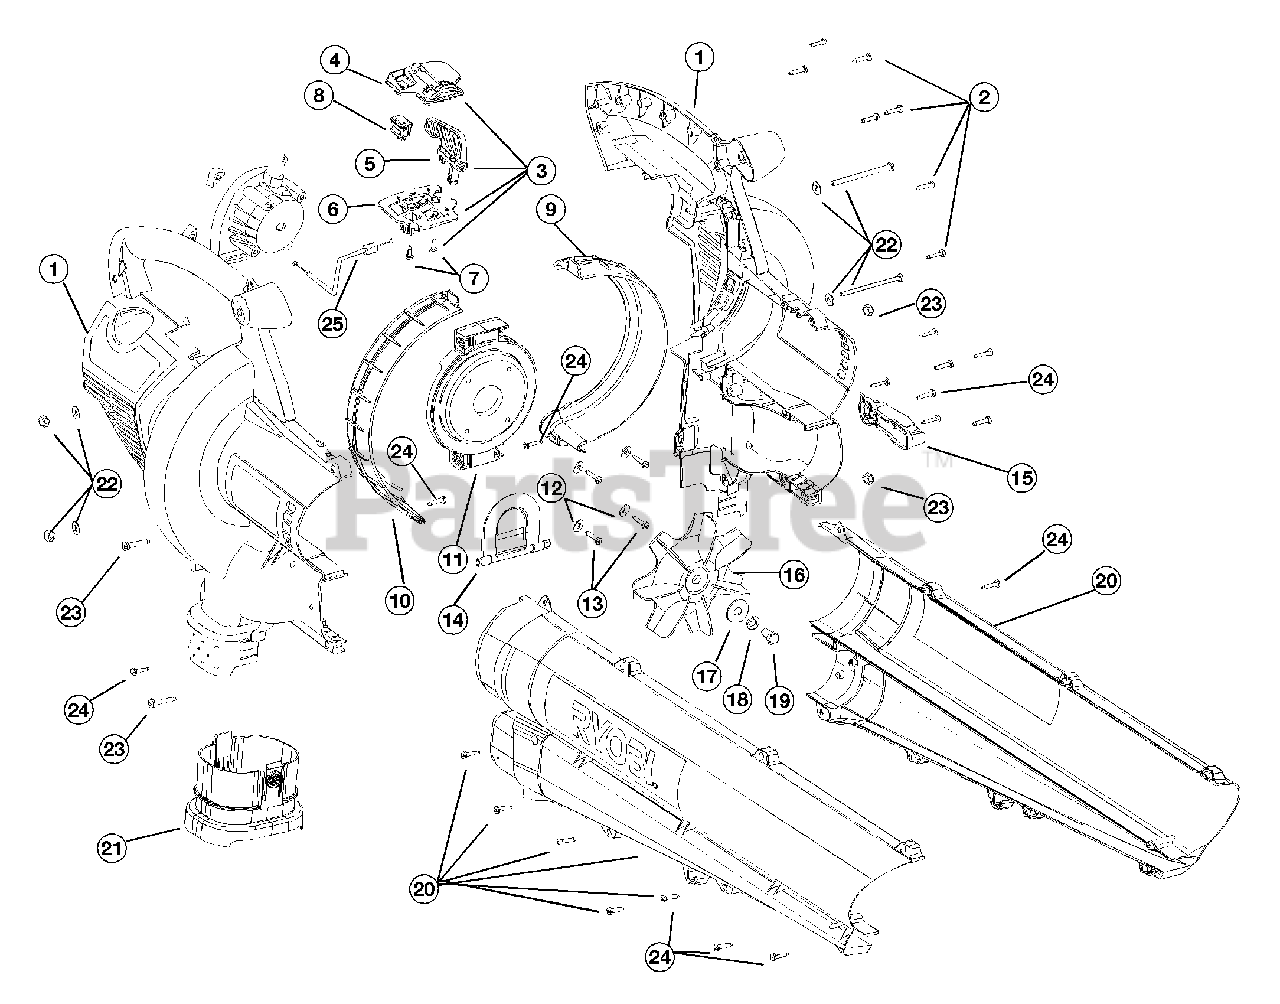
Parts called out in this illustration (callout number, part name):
1	Engine Cover
3	Throttle Control Assembly
4	Upper Throttle Control Plate
5	Throttle Control Lever
6	Lower Throttle Control Plate
7	Screw, Plastic
8	Rocker Switch Assembly
9	Left Side Liner
10	Right Side Liner
11	Engine Mounting Plate
14	Mode Control Flapper
15	Mode Control Lever
16	Impeller Blade
17	Washer
18	Lock Washer
20	Blower/Vac Tube Assembly
21	Vacumm Bag Adapter
22	Mounting Plate Hardware
23	Blower/Vac Tube Mounting Hardware
25	Throttle Cable
